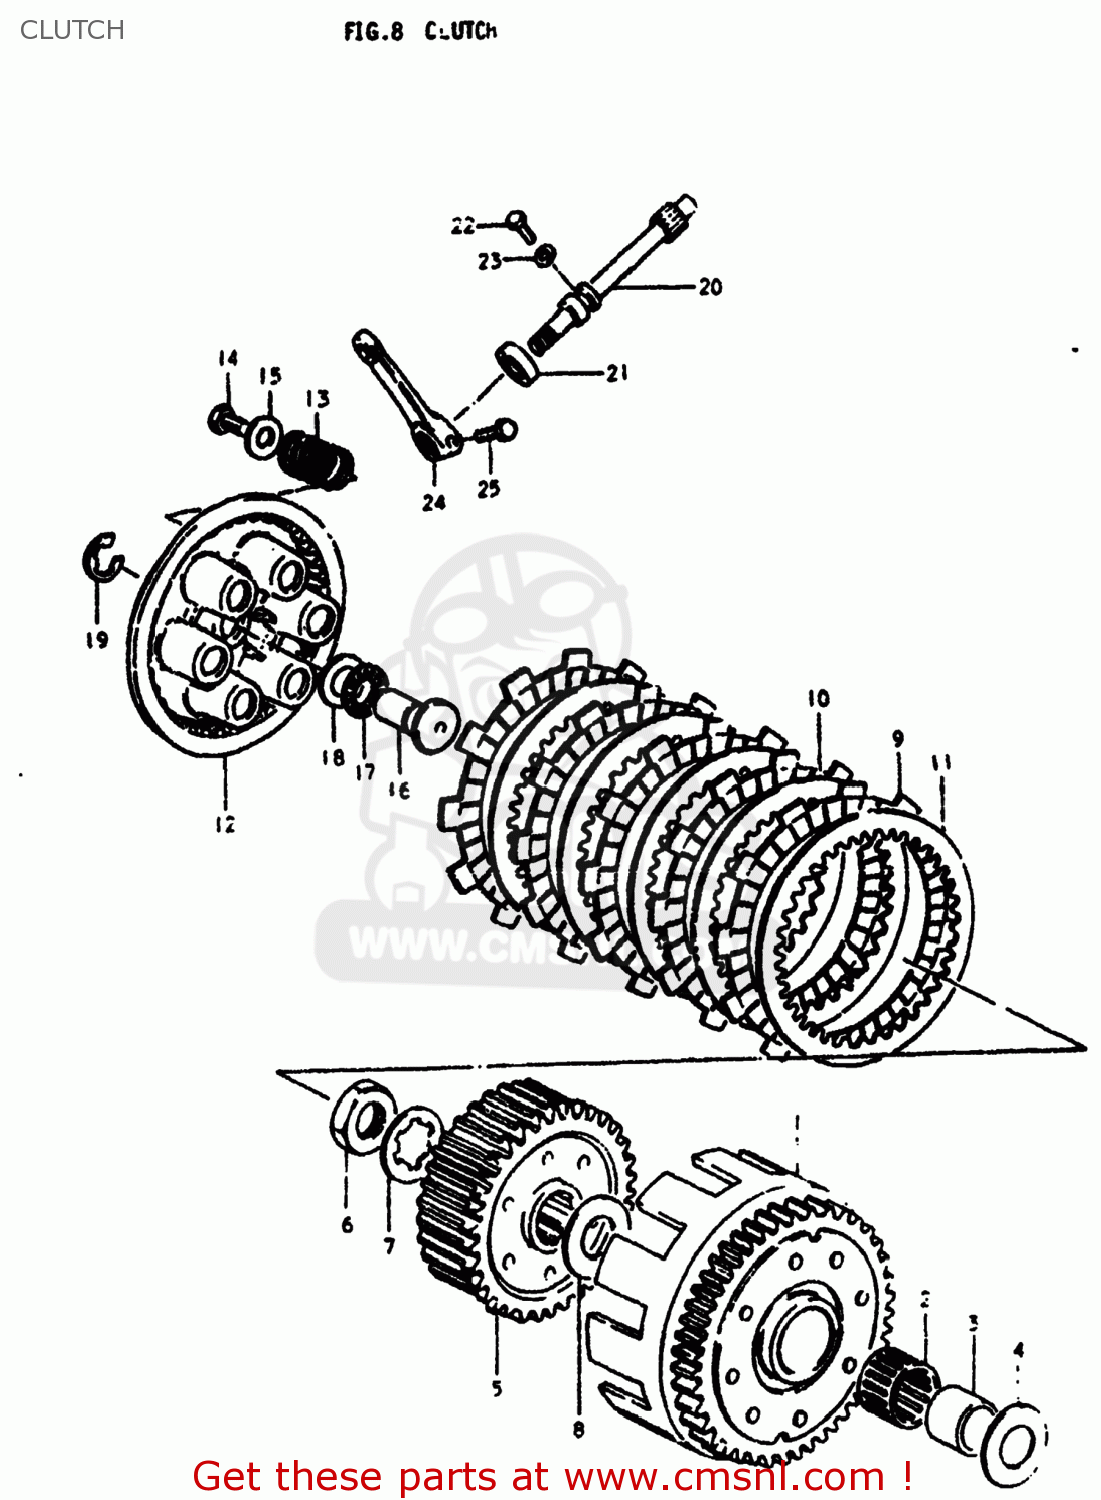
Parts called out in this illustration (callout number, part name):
1	GEAR ASSEMBLY,PRIMARY DRIVE
2	BEARING(30X35X19.8)
3	SPACER
4	WASHER
5	HUB,CLUTCH SLEEVE
6	NUT
7	WASHER,LOCK
8	WASHER
9	PLATE,CLUTCH DRIVE (MCA)
10	PLATE,CLUTCH DRIVEN (NAS)
11	PLATE,CLUTCH DRIVEN(T:2.0) (NAS)
12	DISC,CLUTCH PRESSURE
13	SPRING
14	BOLT
15	WASHER
16	RACK,CLUTCH RELEASE
17	BEARING(15X28X2)
18	WASHER
19	E RING 12MM
20	PINION,CLUTCH RELEASE
21	OIL SEAL
22	BOLT(6X12)
23	WASHER
24	ARM,CLUTCH RELEASE
25	BOLT
